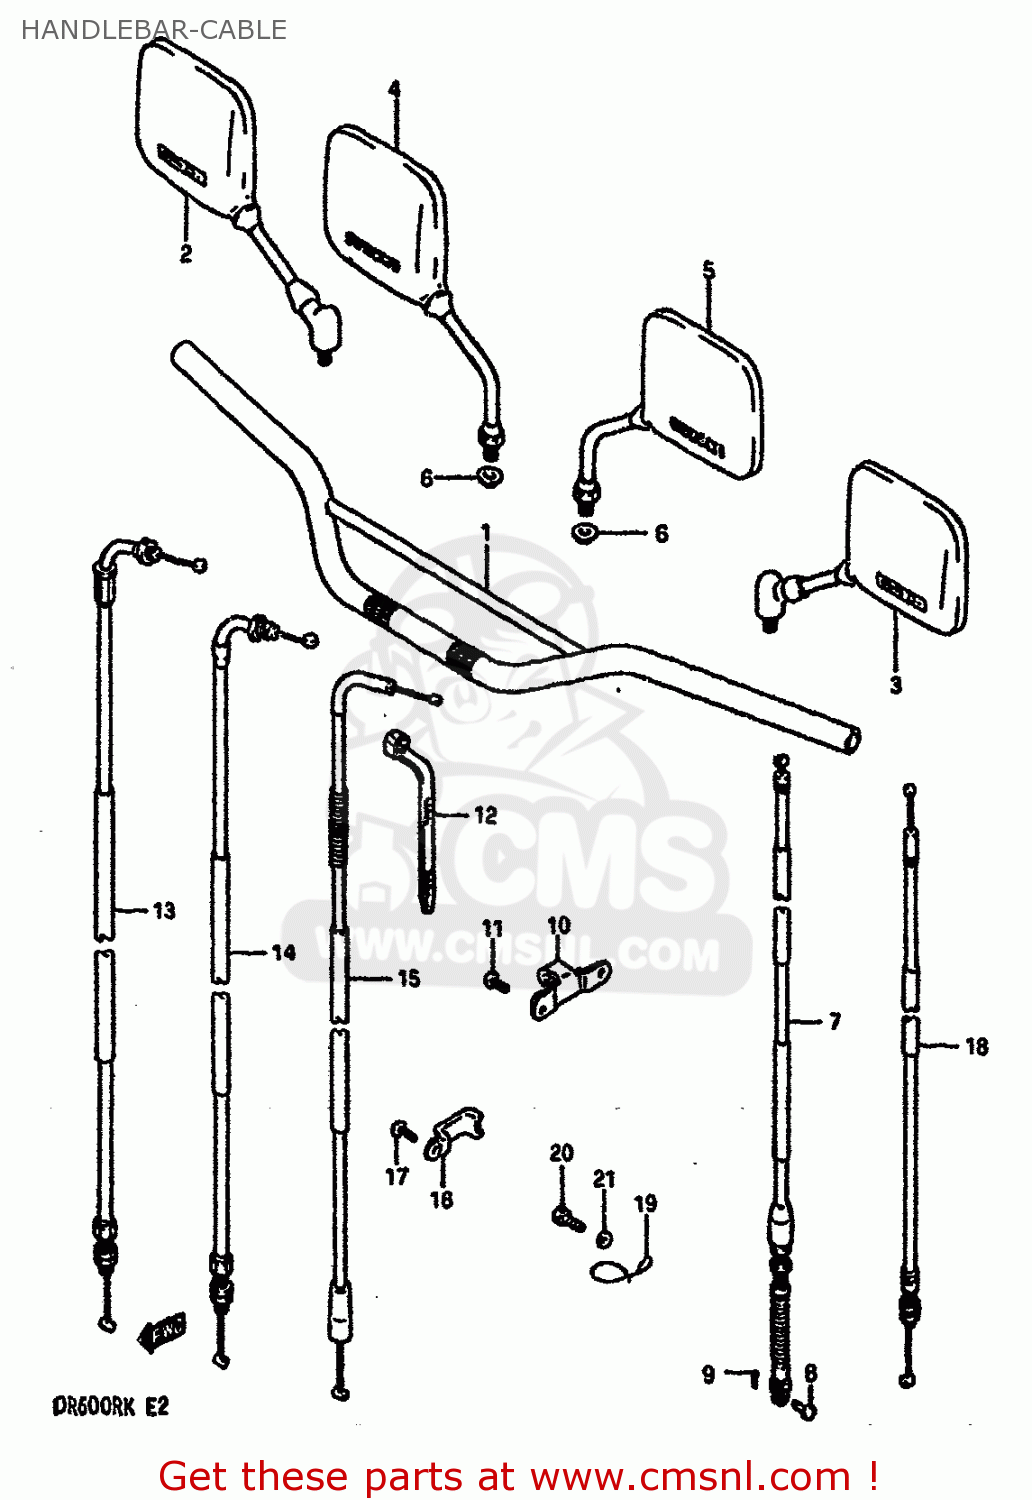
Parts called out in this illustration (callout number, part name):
1	HANDLEBAR
2	MIRROR ASSEMBLY,REAR VIEW
3	MIRROR ASSEMBLY,REAR VIEW
4	MIRROR, REAR VIEW RH
5	MIRROR ASSEMBLY,LEFT
6	WASHER
7	CABLE ASSY,CLUTCH
8	PIN(L:13)
9	PIN
10	STOPPER,CLUTCH CABLE
11	SCREW
12	CLAMP(L:125)
13	CABLE ASSY,THROTTLE NO.1
14	CABLE ASSY,THROTTLE NO.2
15	CABLE ASSEMBLY,THROTTLE
16	CLAMP
17	SCREW
18	CABLE ASSY,DECOMP
19	GUIDE
20	BOLT
21	WASHER,LOCK
